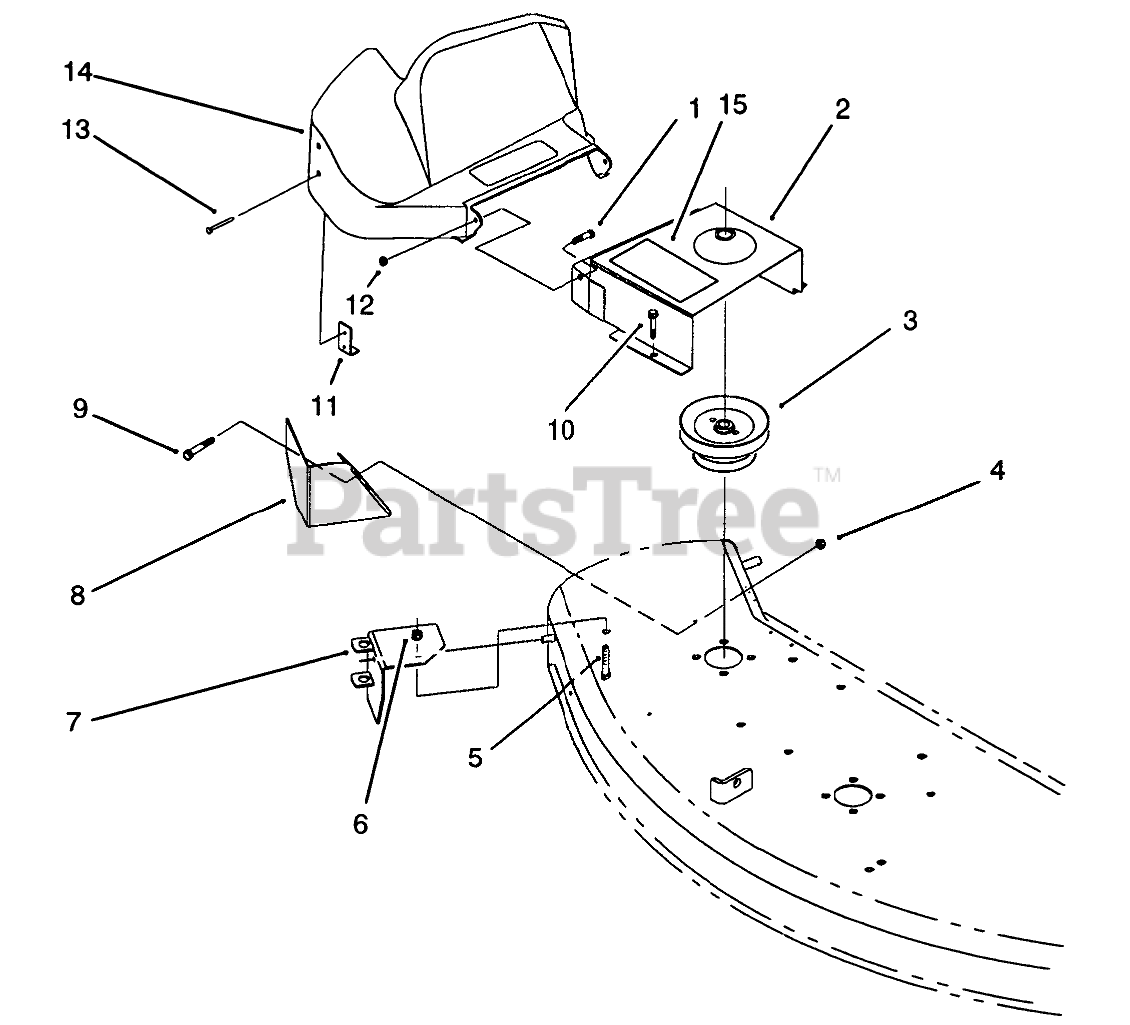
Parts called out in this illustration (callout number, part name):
1	SCREW-HH
2	48" Inner Shield Assembly (Incl. Ref. #15)
3	PULLEY
4	NUT-LOCK, NI
5	SCREW-HH
6	NUT-HF
7	PIVOT SUPPORT ASM
8	48" DEFLECTOR B
9	SCREW-CARR
10	Bolt
11	BRACKET-SUPPORT, SHIELD
12	NUT-LOCK, NI
13	RIVET-POP
14	SHIELD-BELT
15	DECAL-DANGER, THROWN OBJECT
